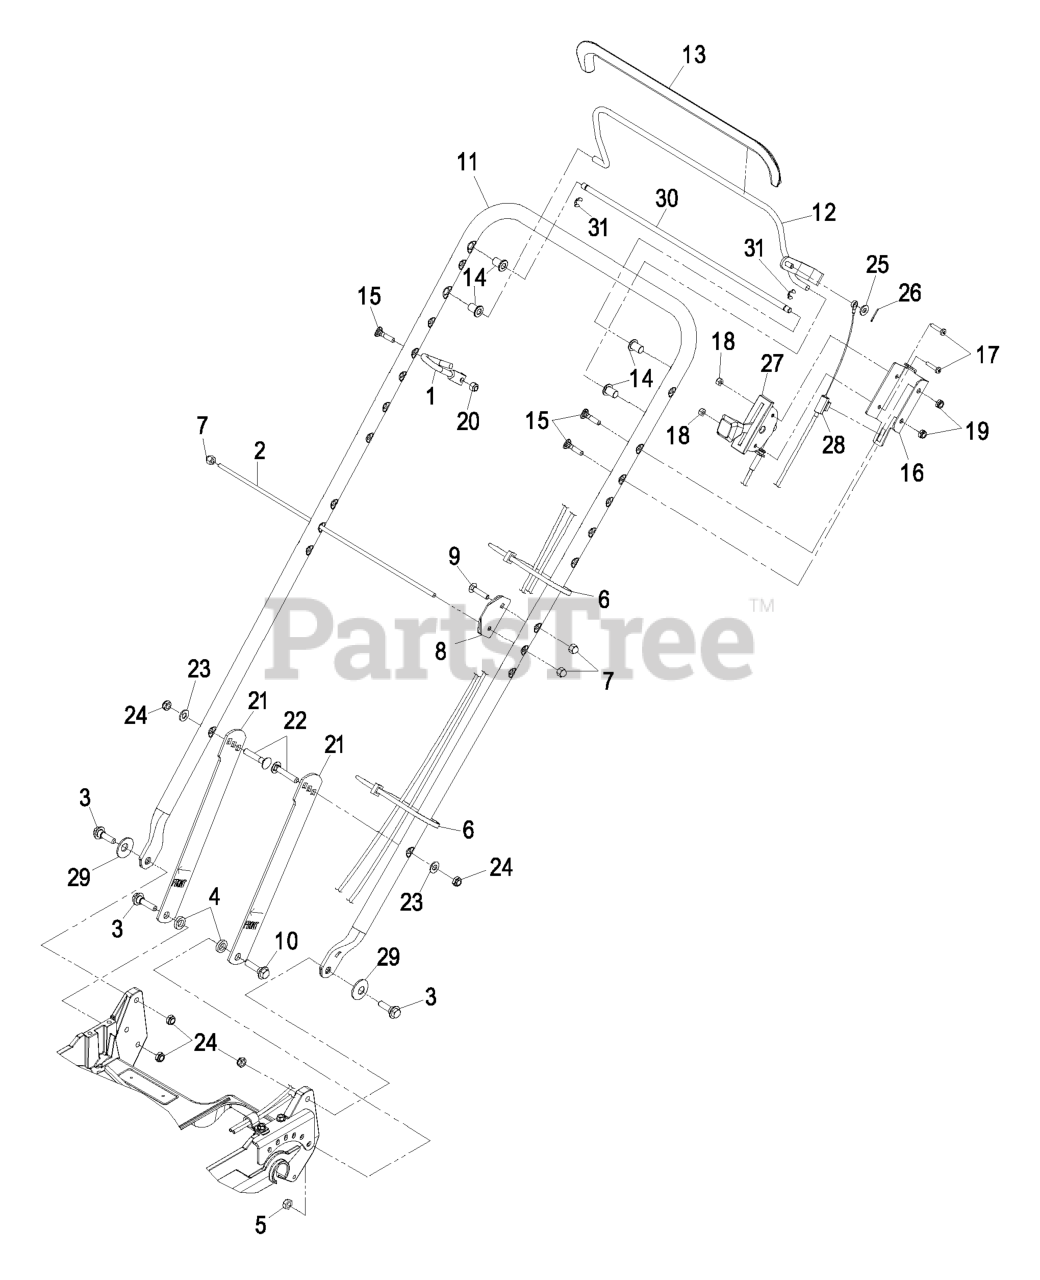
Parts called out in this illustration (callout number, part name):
1	GUIDE-ROPE
2	ROD,BAG SUPPORT
3	SCREW-SHOULDER
4	SPACER
5	NUT-LOCK, NI
6	TIE-CABLE
7	NUT-CAP
9	SCREW-CARR
10	SCREW-SHOULDER
12	WLD,BAIL DEADMAN (PLATED)
13	PAD,DEADMAN
14	BUSHING
15	SCREW-HANDLE
16	BRACKET,THROTTLE
17	SCREW-PPH
18	NUT-LOCK, NI
19	NUT-LOCK, NI
20	NUT-LOCK, NI
22	BOLT-CARR
23	WASHER-PLAIN
24	NUT-LOCK, NI
25	WASHER-FLAT
26	PIN-COTTER
27	CABLE,THROTTLE KAWASAKI
28	CABLE,BRAKE KAWASAKI
29	WASHER-SPRING
30	ROD,BAIL STOP
31	RING-CLIP
